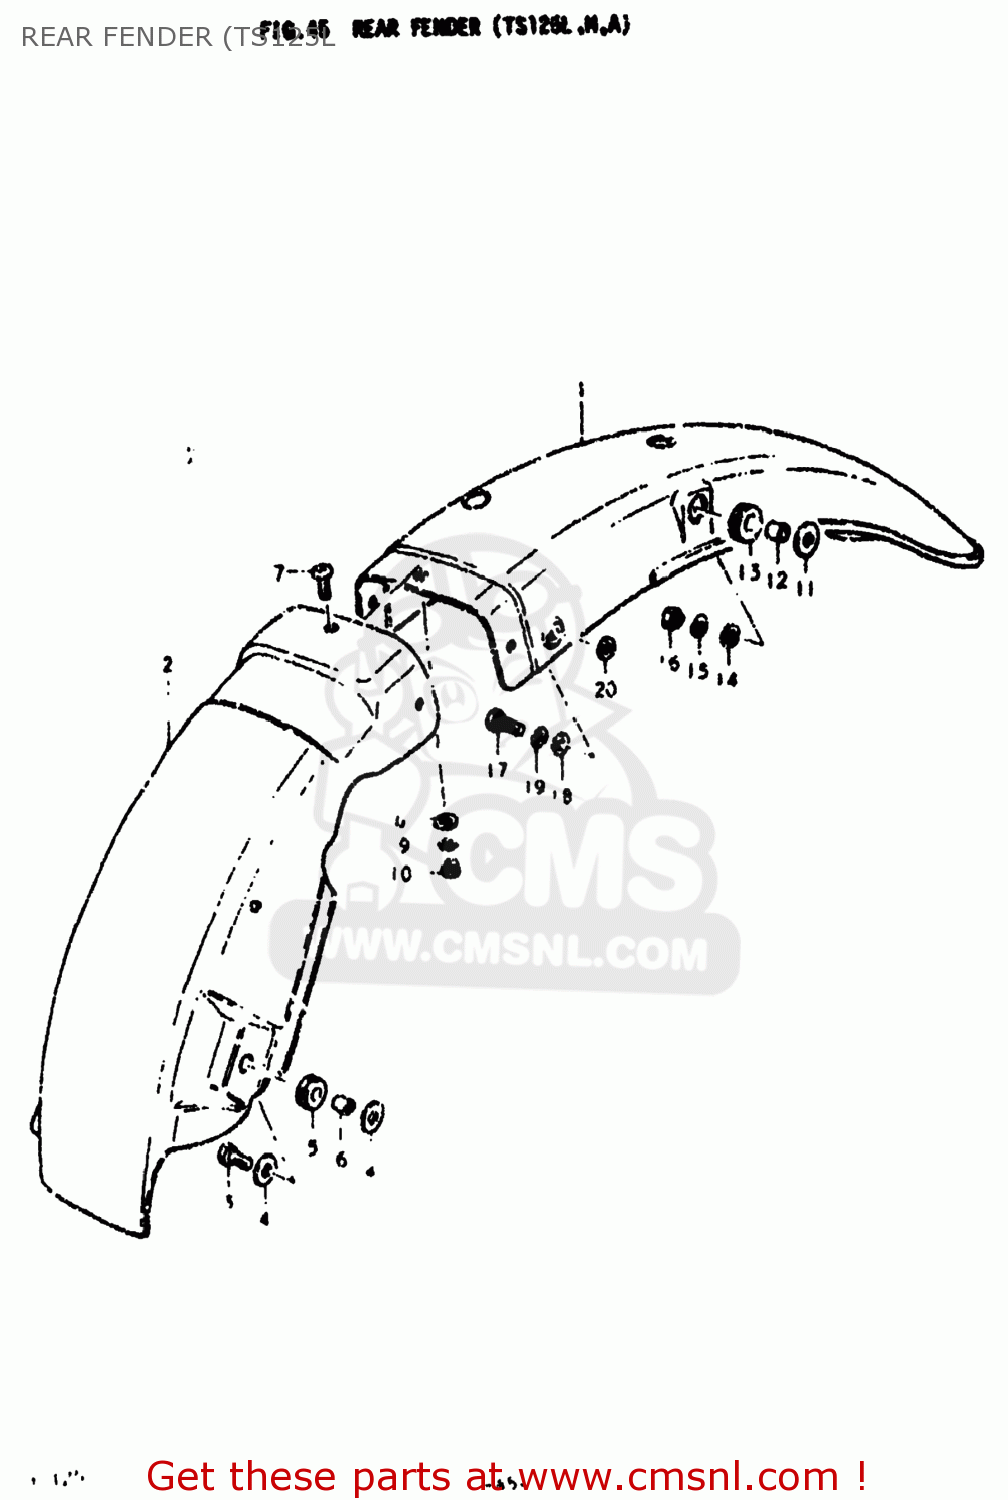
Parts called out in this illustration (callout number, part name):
1	FENDER,REAR
2	FENDER,REAR
3	BOLT
4	WASHER (6.5X20X1.2)
5	CUSHION
6	SPACER(6.1X9X7.5)
7	SCREW
8	WASHER 5MM
9	LOCK WASHER
10	NUT
11	WASHER(10.3X25X1.5
12	SPACER
13	CUSHION
14	WASHER(10.3X25X1.5
15	LOCK WASHER
16	NUT
17	BOLT
18	WASHER
19	LOCK WASHER
20	WASHER(10.3X25X1.5
